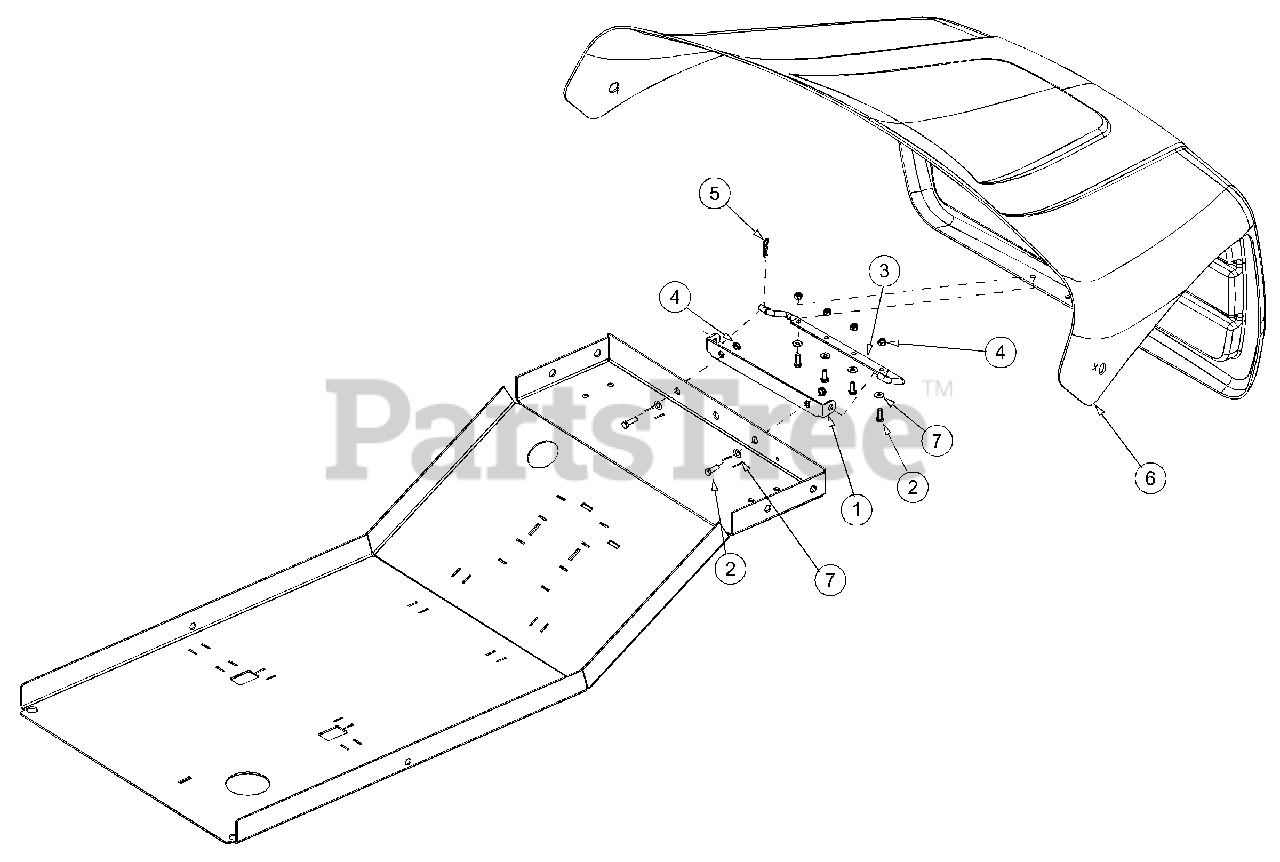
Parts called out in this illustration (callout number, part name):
3	Rod Mounting Hood
4	Nut, Nylon Hex Lock, 1/4-20, Gr8
5	Cotter Pin
6	Panel, Hood
7	Washer, Flat, .271 x .630 x .065
